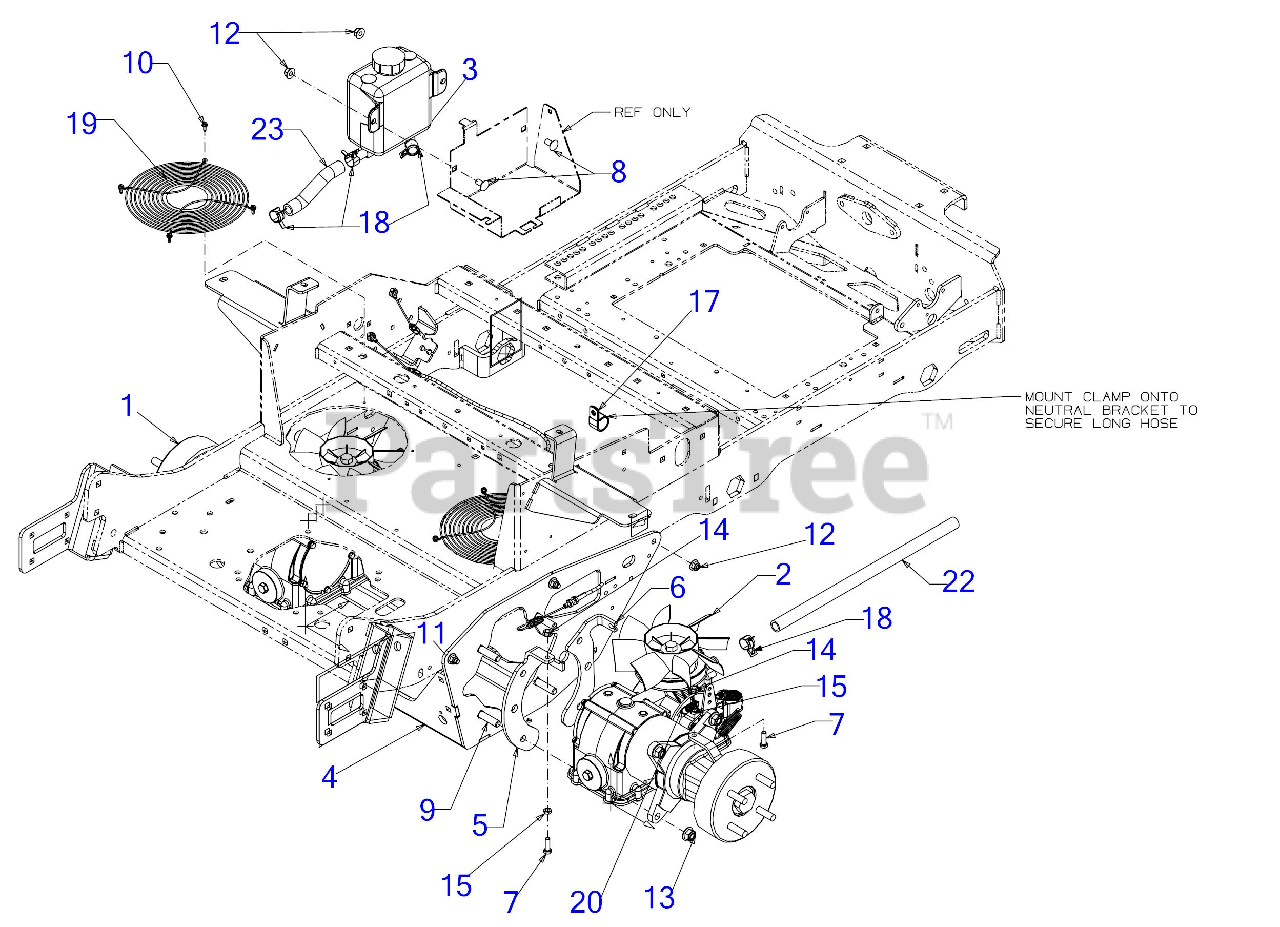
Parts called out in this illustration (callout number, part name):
1	TRANSMISSION ASSEMBLY PARKER (LH)
2	TRANSMISSION ASSEMBLY PARKER (RH)
3	HYDRO TANK ASSEMBLY
7	SCREW 5/16-18 x 1.0 GR5
8	CARRIAGE BOLT 3/8-16 x .750 GR5
9	CARRIAGE BOLT 1/2-13 GR5
10	SCREW 10-24 x 0.500
11	CARRIAGE BOLT 3/8-16 X1.25 GR5
14	HEX FLANGE NUT
17	HOSE CLAMP 1.0"
18	HOSE CLAMP
20	EXTENSION SPRING .500 OD x 1.71
22	OIL HOSE 5/8 ID X 18.00 LG
